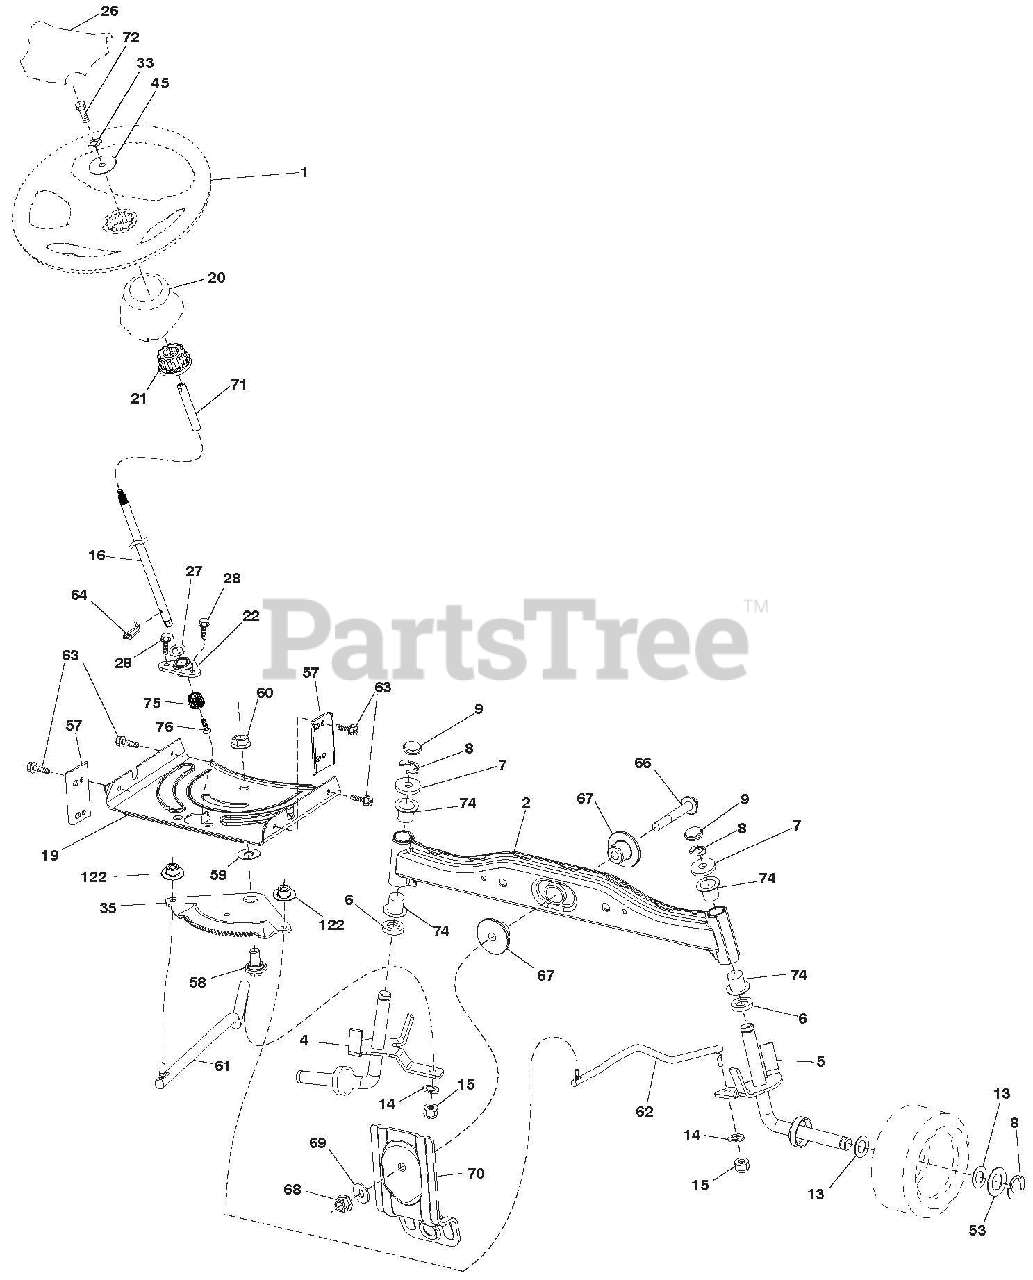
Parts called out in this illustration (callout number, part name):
1	WHEEL.STEERING.HARD RIM.BLACK
2	AXLE ASM.WELDED
4	SPINDLE.WELDED.LH.15"TEX
5	SPINDLE.WELDED.RH.15"TEX
6	WAHSER THRUST .75 X 1.230
7	WASHER.25/32 X 1-5/8 X 16GA.
8	RING.KLIP.#T5304-75
9	CAP.SPINDLE.FR.TOP.BLK.
13	WASHER.25/32 X 1 1/4 X 16 GA.
14	Washer, Lock 3/8
15	NUT.CROWNLOCK.3/8-24
16	STEERING SHAFT
19	PLATE.STEER.DDL.NLT/NGT
20	BOOT.STEERING.LT.TEX P/L.428
21	ADAPTER.WHEEL.STRG..760
22	STEER.SUPT. LOWER
26	CAP.WHL.STRG.HRS/SRS.BLACK
27	Washer 21/32 x 1 x 16 Ga.
28	SCREW.HEXWSH THDR3/8-16X3/4.BL
33	Washer, Lock 5/16
35	GEAR SECTOR.PLATE.DDL.NLT/NGT
45	WASHER.11/32ID X2 3/8OD X 12GA
53	WASHER.HARDEN..793 X 1.637X060
57	BRACKET.UPSTOP.TEX
58	BOLT.SHOULDER.SECTOR.PIVOT.CFM
59	WASHER.THRUST.SECTOR.STEER.NLT
60	NUT.FLANGE LOCK.5/8-11
61	DRAGLINK.LH.BALLSTUD.DDL.
62	DRAGLINK.RH.BALLSTUD.DDL
63	SCREW.5/16-18X3/4.SMGML.TAP/BL
64	RETAINER.CLIP.SPRING.STEERING
66	BOLT.HEX.FGHD.7/16-14 X 3.SERR
67	BUSHING.PM.FRONT AXLE
68	NUT.LOCK.FLANGE.7/16-14.GR5
69	WASHER.1.5 X .505 X .118
70	BRACKET
71	Extension Steering
72	Bolt 5/16-18 x 14 w/Patch
74	BEARING COL STRNG BLK
75	PINION
122	CAP GEAR SECTOR
